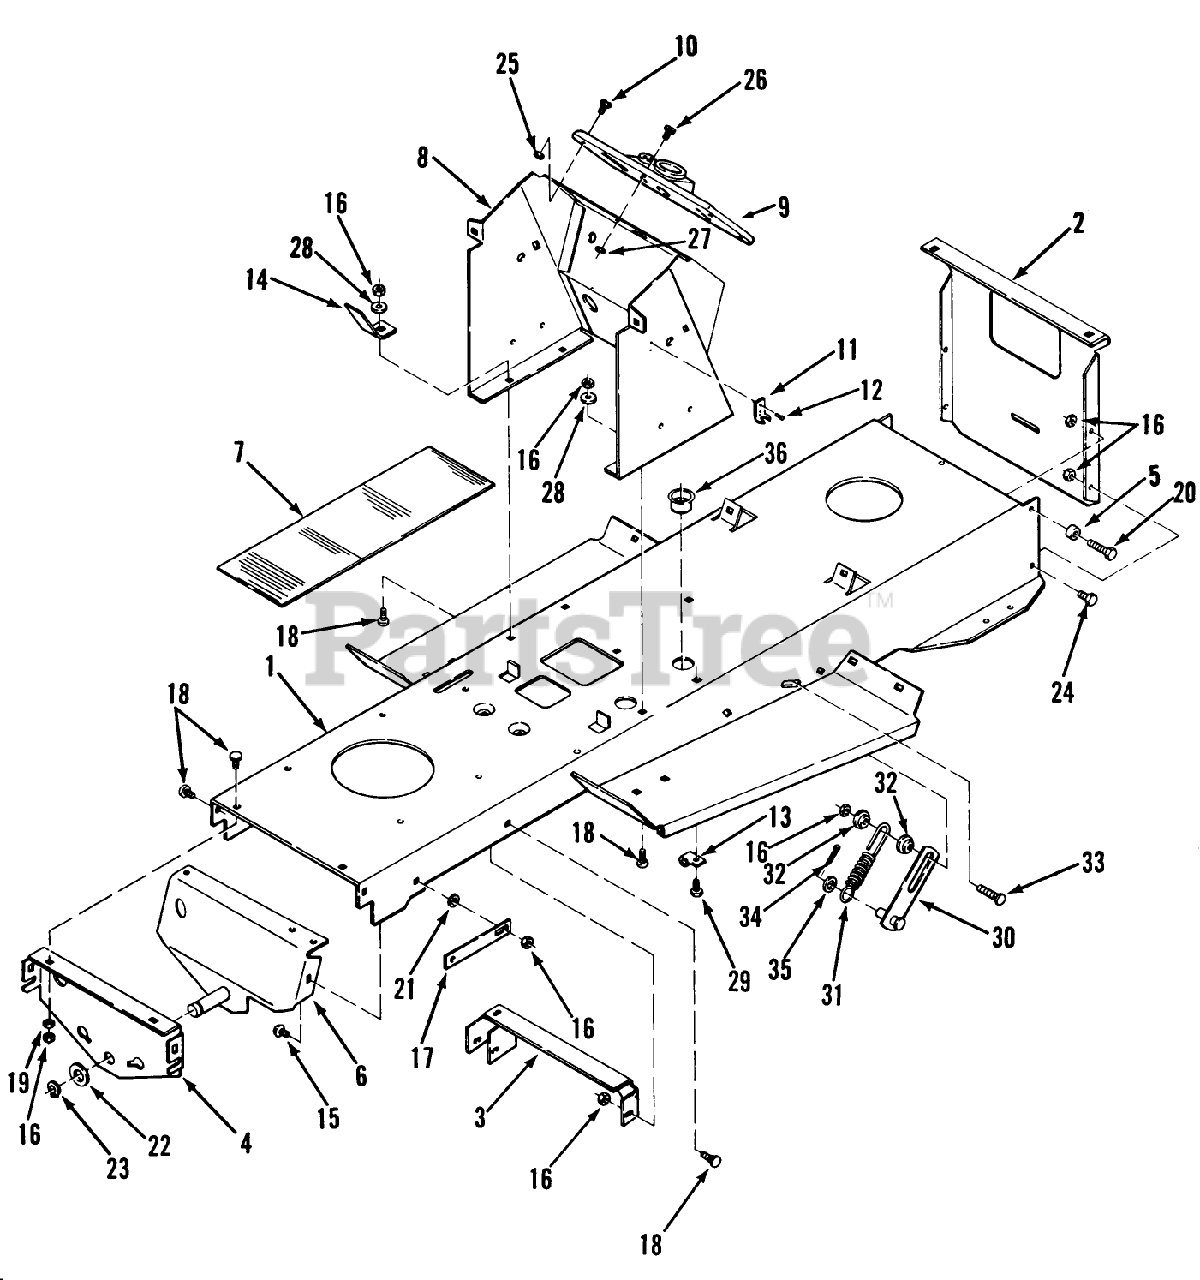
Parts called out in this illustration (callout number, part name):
2	PLATE DRAWBAR
4	PLATE SUPT - AXLE *R
5	BEARING CAM ROLLER
7	PAD-FOOTREST
11	ASSY-FLEX DRAW LATCH
13	J-CLIP
17	STRAP *R
19	LOCKWASHER
22	WASHER
31	SPRING
35	WASHER-FLAT
36	BUSHING-NYLON 1.093
